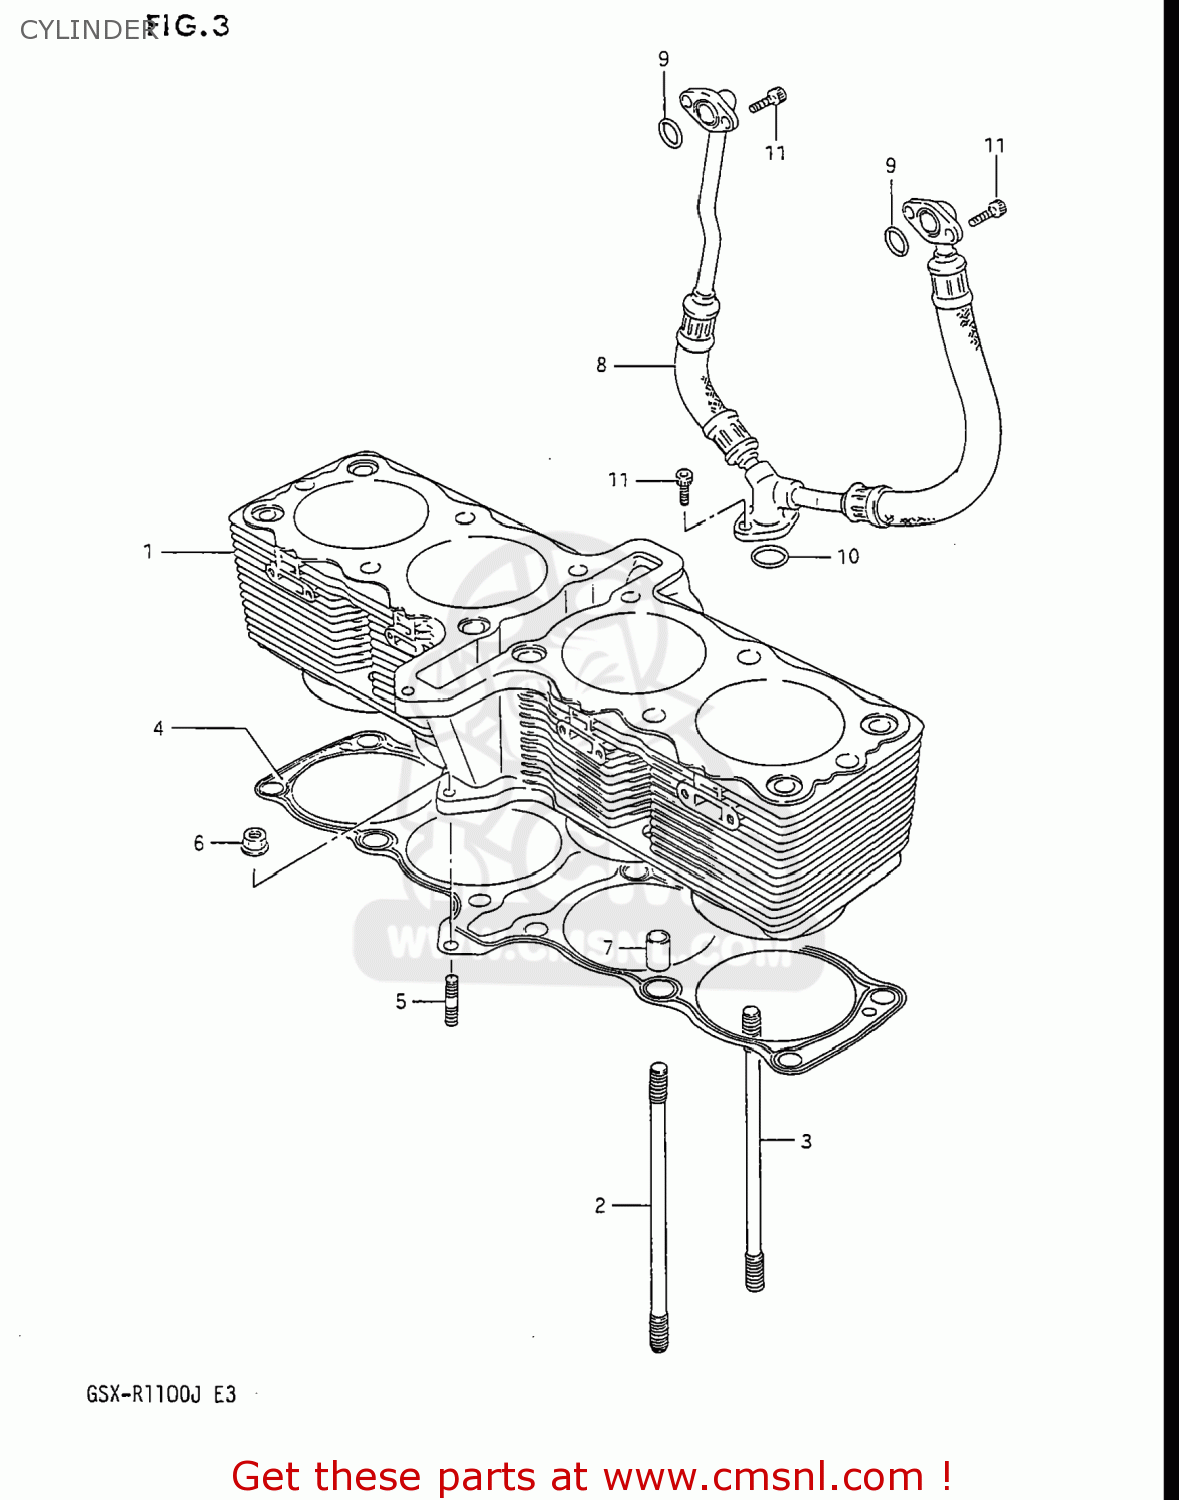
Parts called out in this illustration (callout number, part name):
1	CYLINDER
2	BOLT,STUD
3	STUD
4	GASKET,CYLINDER (NAS)
5	STUD BOLT L:20
6	NUT 6MM
7	PIN
8	HOSE
9	O RING(D:2.5,ID:13.8)
10	O RING(D:2.4,ID:15.8)
11	BOLT
